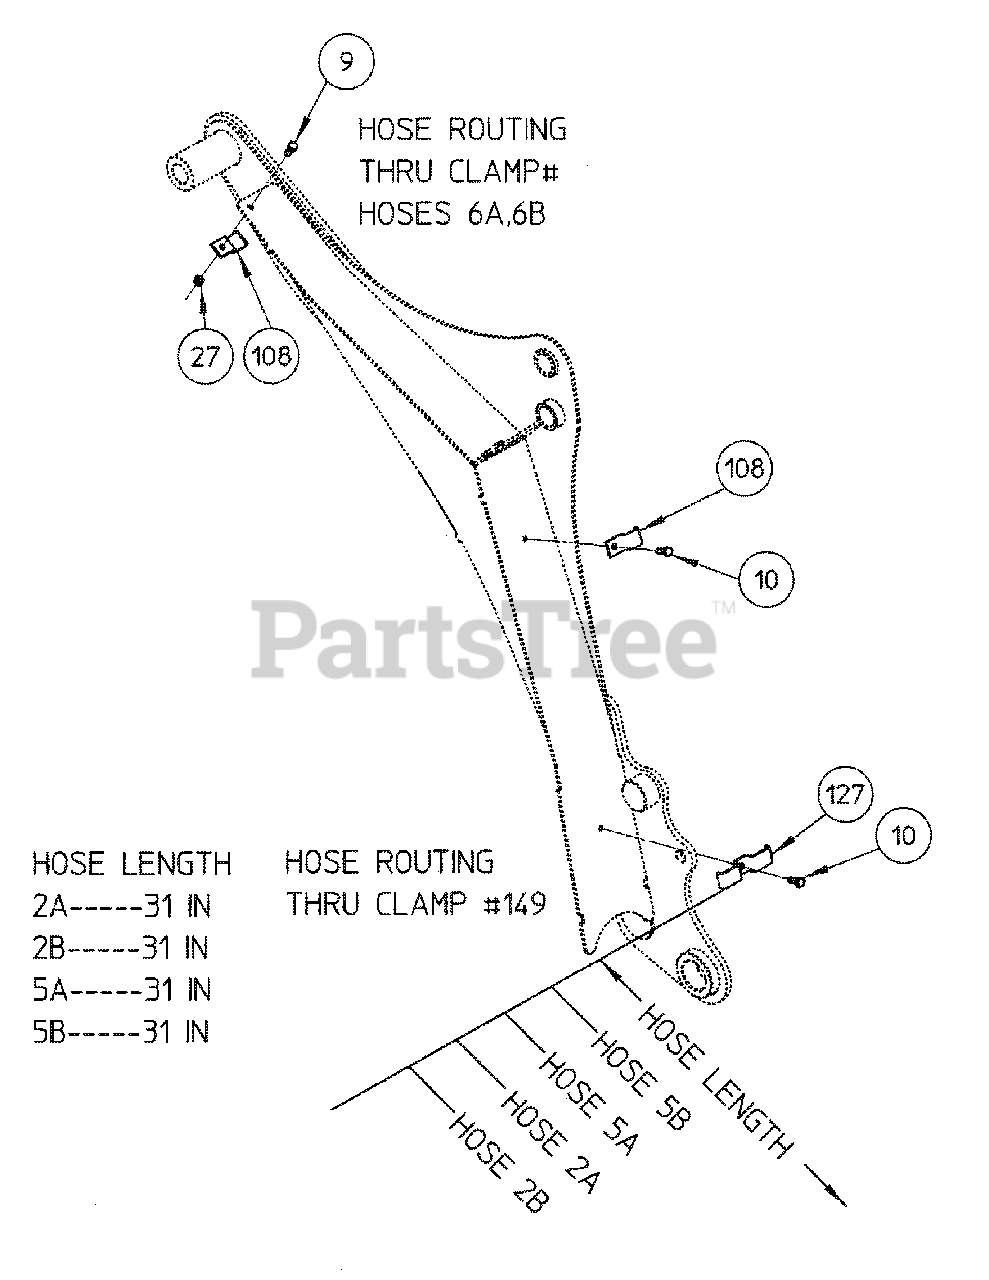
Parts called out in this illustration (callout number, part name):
1	Hydraulic Cylinder - Swing
2	Hydraulic Cylinder - Bucket
3	Hydraulic Cylinder - Stabilizer
4	Hydraulic Cylinder - Boom
5	Hydraulic Cylinder - Dipper
6	Bolt, Carriage 5/16 NC x 3/4"
7	Bolt, Carriage 5/16 NC x 1-1/4"
8	Bolt, 1/4 NC x 3/4"
9	Bolt, 5/16 NC x 3/4"
10	Bolt, 5/16 NC x 3/4" Thread Forming
11	Bolt, 5/16 NF x 3/4"
12	Bolt, 5/16 NF x 7/8"
13	Bolt, 5/16 NF x 1" Gr. 5
14	Bolt, 5/16 NF x 2-1/4" Gr. 5
15	Bolt, 5/16 NF x 2-1/2" Gr.5
16	Bolt, 5/16 NF x 4" Gr. 8
17	Bolt, 3/8 NF x 3/4"
18	Bolt, 3/8 NF x 1"
19	Bolt, 3/8 NF x 1-1/4"
20	Bolt, 3/8 NF x 1-3/4"
21	Bolt, 3/8 NF x 2-1/4"
22	Bolt, 3/8 NF x 2-3/4"
23	Bolt, 3/8 NC x 5-1/2" Long Gr.5
24	Bolt, 1/2 NF x 7/8"
25	Nut, 1/4 NC
26	Nut, 5/16NC
27	Locknut, 5/16 NC
28	Nut, 5/16 NF
29	Locknut, 5/16 NF
30	Lock Nut, 3/8NC
31	Locknut, 3/8 NF
32	Lockwasher, 1/4
33	Lockwasher, 5/16
34	Flat Washer. 5/16 STD
35	Washer, 5/16 SAE
36	Flat Washer, 3/8 SAE
37	Flat Washer, 1/2" Hardened
38	Machine Bushing, 1-1/4 OD x 3/4 ID x 14Ga.
39	Machine Bushing 1-1/2" OD x 1" ID x 18Ga.
40	Machine Bushing 1-7/8" OD x 1-1/4" ID x 18Ga.
41	Machine Bushing, 2-1/2 OD x 1-3/4ID x 18Ga
42	Cotter Pin, 3/32" Dia x 3/4"
43	Cotter Pin, 3/16 x 1-1/4"
44	Cotter Pin, 1/4 x 1-1/2"
45	Hair Pin Cotter, 3/64" Dia x 11/16"
47	Adapter Union, 9/16-18M x 3/8NPTF
48	Hydraulic Tee
49	Adapter Union, 3/4-16M x 3/8NPTF x Straight
50	Adapter Union, 3/8NPTM x 3/8NPTF x 90 degree
51	Adapter Union, 9/16-18M x 3/8NPTF x 90 degree
52	Adapter Union, 7/8-14M x 3/8 NPTF x 90 degree
53	Adapter Union, 3/4-16M x 3/8NPTF x 90 degree
54	Coupler Body 3/4-16F Thread
55	Coupler Nose 3/4-16F Thread
56	Garlock Bearing, 028DXR020
57	Bronze Bearing
58	Garlock Bearing, 028DXR016
59	Stabilizer Pad Weldment
60	Guide Link
61	Bucket Link
62	Street Pad
63	Clevis Pin, 3/16" Dia x 5/8"
64	Clevis Pin, 1/4" Dia x 7/8"
65	Pin Retainer
66	Pin Retainer
67	Boom Lock Pin
68	Swing Lock Pin
69	SMV Socket
70	SMV Bracket
72	Ball Joint - Shouldered
73	Ball Joint
74	Control Knob
75	Rubber Cap
76	Plastic Tie T150L
77	Plastic Tie T120 L
78	Plastic Tie T50L
80	Hose Sleeve FC425-16 X 30" Long
81	Hose Sleeve FC425-16 X 19" Long
82	Hose Sleeve FC425-16 X 48" Long
83	Hose Sleeve FC425-16 X 63" Long
84	Hose Sleeve FC425-16 X 79" Long
85	Grease Fitting
86	Grease Fitting (Two are part of #000187 Cyl.)
87	Grease Fitting (Two are part of #000187 Cyl.)
88	Hydraulic Hose, 3/8NPTM x 3/8NPTM x 20" long
89	Hydraulic Hose, 3/8NPTM x 3/8NPTM x 23" long
90	Hydraulic Hose, 3/8NPTM x 3/8NPTM x 30" long
91	Hydraulic Hose, 3/8NPTM x 3/8NPTM x 58" long
92	Hydraulic Hose, 3/8NPTM x 3/8NPTM x 76" long
93	Hydraulic Hose, 3/8NPTM x 3/8NPTM x 92" long
94	Hydraulic Hose, 3/8NPTM x 3/8NPTM x 110" long
95	Hyd. Hose, 3/8ID 3/8NPTF M x 3/4-16 Str O x 49"
96	Hyd. Hose, 3/8ID 3/8NPTF M x 3/4-16 Str O x 34"
97	Control Valve
98	Adapter Union, 7/16-20M x 3/8NPTF
99	Rear Shroud
100	Stabilizer Lever Control Rods
101	Control Rod
102	Pivot Pin, Boom Cyl. Rod 1-1/4" Dia. x 6" Long
103	Thrust Washer
104	Pivot Pin, Bucket 1"Dia. x 7-3/8" Long
105	SMV Socket Mount
106	Stabilizer Control Lever
107	Lever Bracket
108	Hose Clamp - Short
109	Pivot Pin, 3/4" Diameter x 4-1/16" Long
110	Pivot Pin, Dipperstick 1-1/4" Dia. x 7-15/16" Long
111	Pivot Pin, Stabilizer Leg
112	Pivot Pin Weldment
113	Pivot Pin, Stabilizer Pad 3/4" Dia. x 4-15/16" Long
114	Pivot Pin, Stabilizer Cyl. Rod
115	Pivot Pin, Bucket Cyl. Base 1" Dia. x 5-7/8" Long
116	Pivot Pin, Boom Cyl. Base 1-1/4" Dia. x 7-1/4" Long
117	Lower Pivot Pin Weldment
118	Seat Plate Weldment
119	RH Pivot Weldment
120	LH Pivot Weldment
122	Stabilizer Leg Weldment
123	Upper Pivot Pin Weldment
124	Pivot Pin Weldment, Boom 1-3/4" Dia. X 2-3/4" Lg
125	RH Toe Shield
126	LH Toe Shield
127	Hose Clamp - Long
128	Grab Bar Weldment
129	Mainframe Weldment
130	Valve Mount Weldment
131	Swing Frame Weldment
132	Front Shroud Weldment with Decals
133	Dipperstick Weldment
134	Boom Weldment
135	Right Hand Joystick Weldment
136	Left Hand Joystick Weldment
